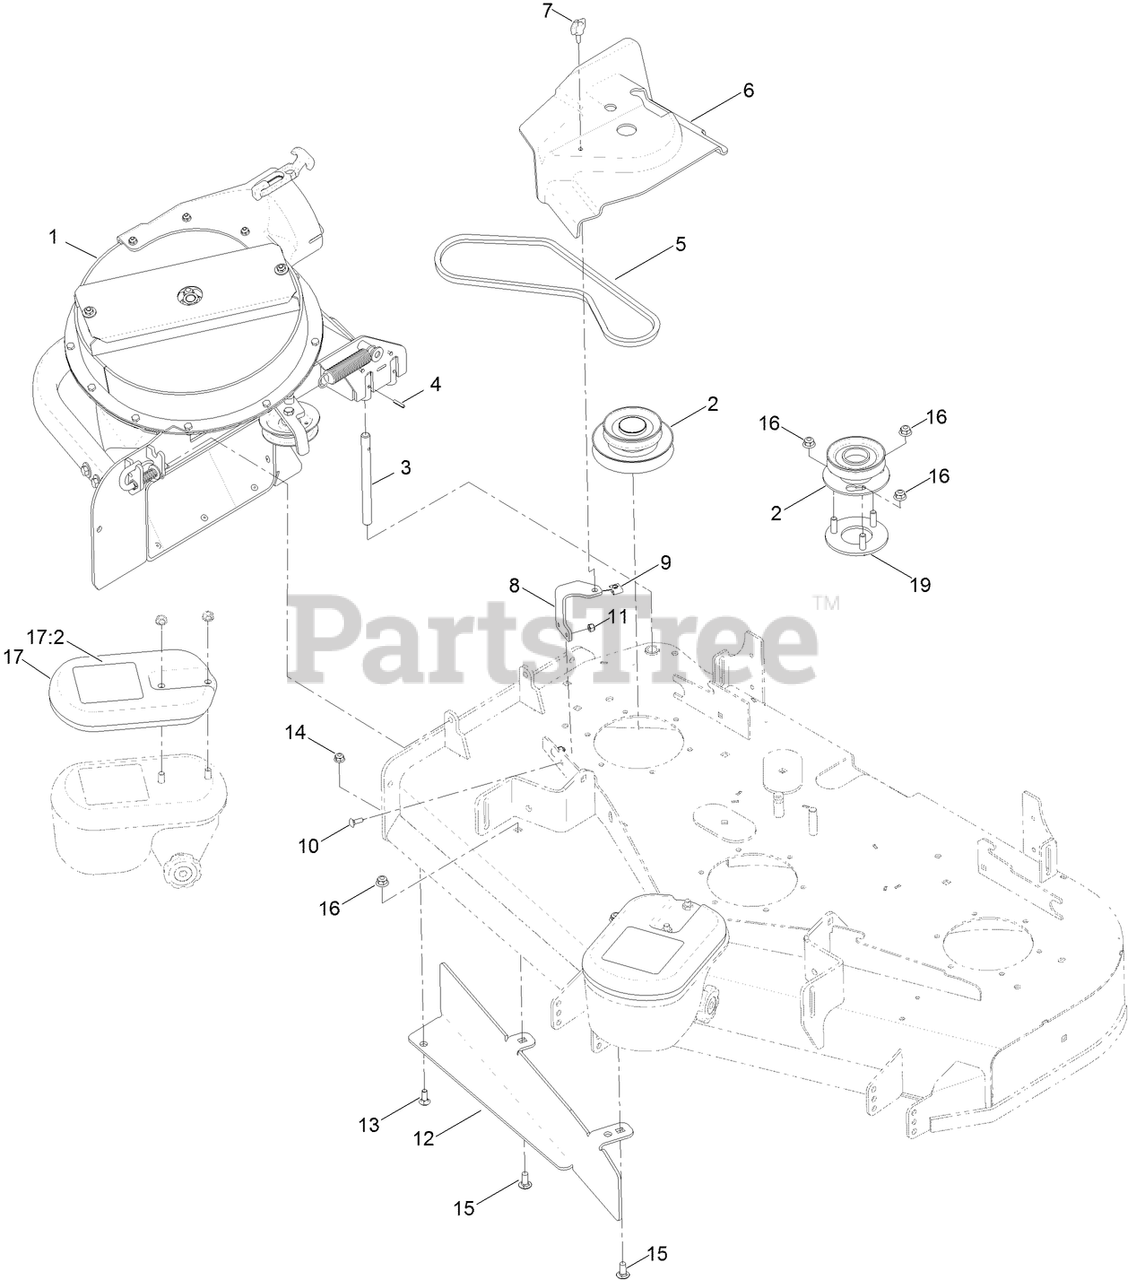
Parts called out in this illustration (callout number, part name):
1	BLOWER ASM
2	PULLEY-BLOWER
3	SHAFT-CATCHER, GRASS
4	PIN-ROLL
5	Belt-V
6	COVER-BELT
8	BRACKET-COVER, BELT
9	NUT-SPEED
10	BOLT-CARR
11	NUT-LOCK, NI
12	BAFFLE-BAGGER, 48 INCH
13	SCREW-CARR
14	NUT-HF, NI
15	SCREW-CARR
16	NUT-HF, NI
17	WEIGHT
17:2	DECAL-WARNING, TRACTION
19	MOUNT-PULLEY
